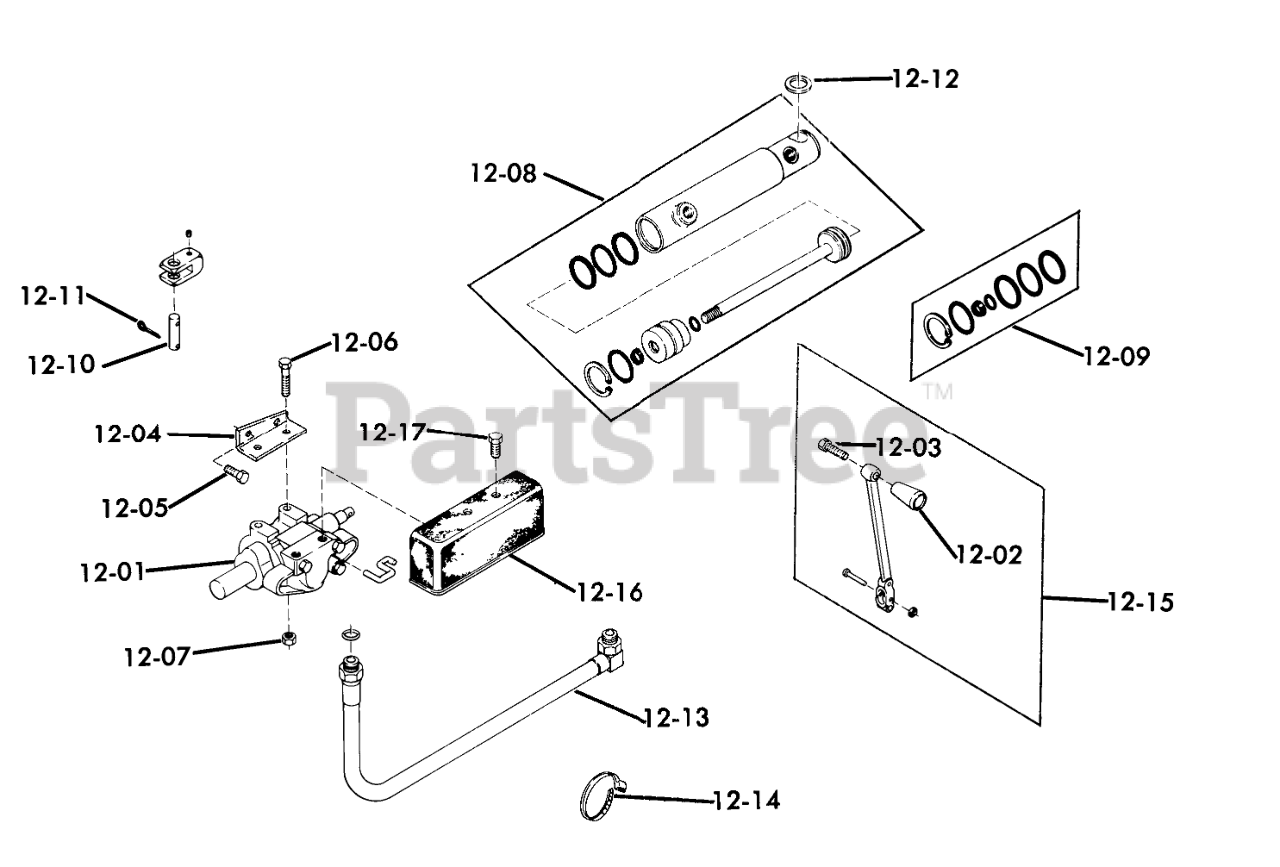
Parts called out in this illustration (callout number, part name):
12-01	Valve
12-03	SCREW
12-04	SUPPORT-VALVE
12-05	Bolt
12-06	Bolt 1/4-20 X 1 1/2
12-07	Nut
12-08	CYLINDER ASSY R
12-09	S/A O-RING&GASKET AS
12-10	PIN
12-12	Spacer
12-13	16" Hose Assembly
12-13	HOSE HYDRAULIC 19"
12-13	ASSY-HYDRAULIC HOSE
12-13	HYD HOSE ASSY
12-14	PLASTIC TIE
12-15	Assy-Handle
12-16	Cover-Valve
12-17	Bolt
